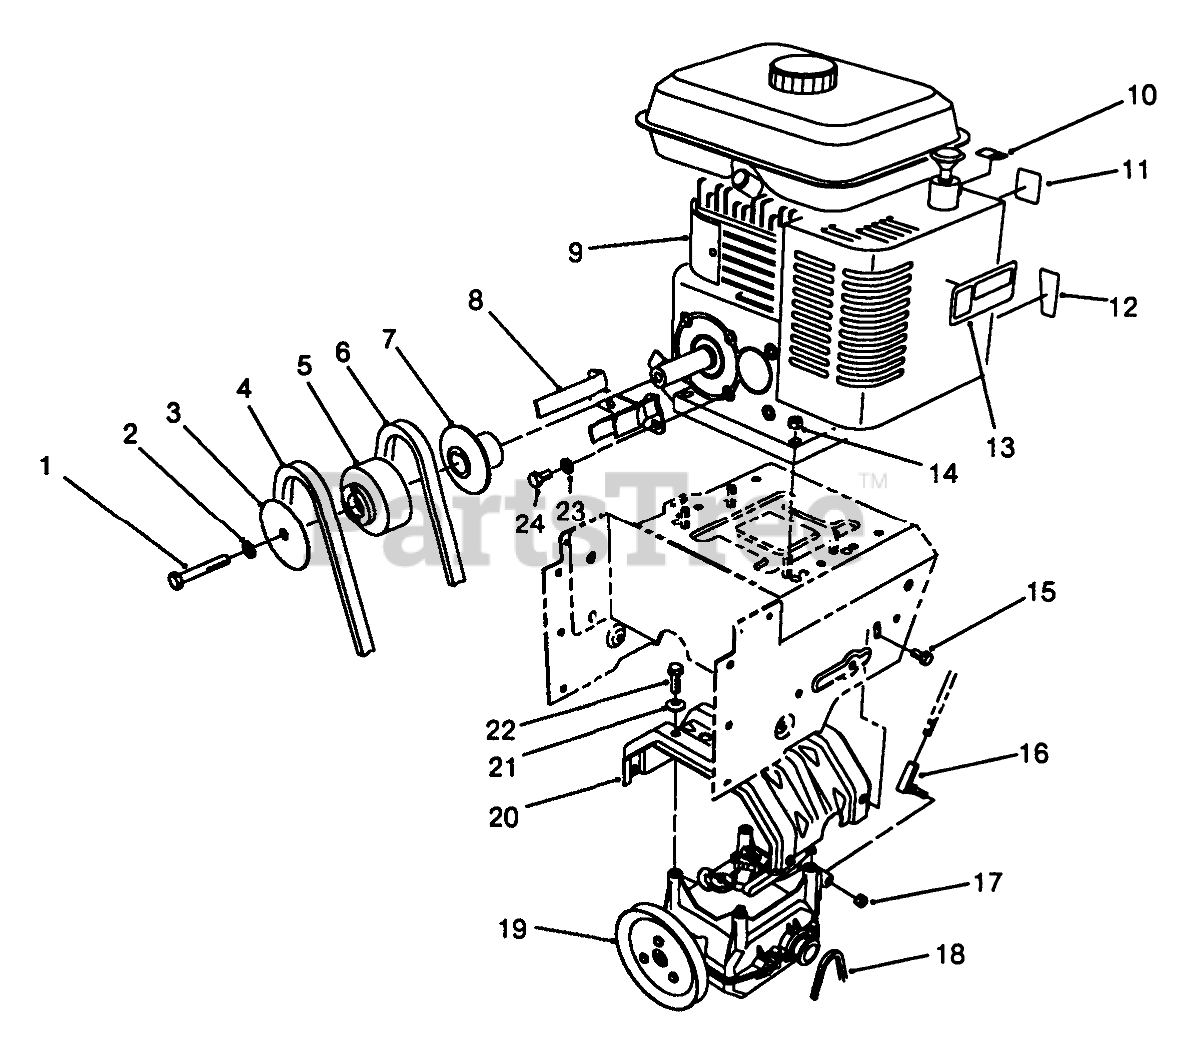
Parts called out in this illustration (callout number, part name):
1	SCREW-HH
2	WASHER-LOCK
3	SHEAVE-HALF,IMPELLER
4	V-BELT
5	ENGINE PULLEY,CENTER
6	Belt-Traction
7	SHEAVE-HALF,TRACTION
8	Guide-Belt
9	Engine-8 hp.
10	DECAL-CHOKE
11	DECAL-PRIMER/CHOKE
12	DECAL-THROTTLE
13	Decal-Hot
14	NUT-HF
15	SCREW-HHF
16	JOINT-BALL
17	NUT-LOCK
18	CHAIN
19	Transmission Assembly
20	Frame-Transmission
21	WASHER-SPRING
22	Screw-Cap Hex Hd.
23	WASHER-LOCK
24	SCREW-HH
